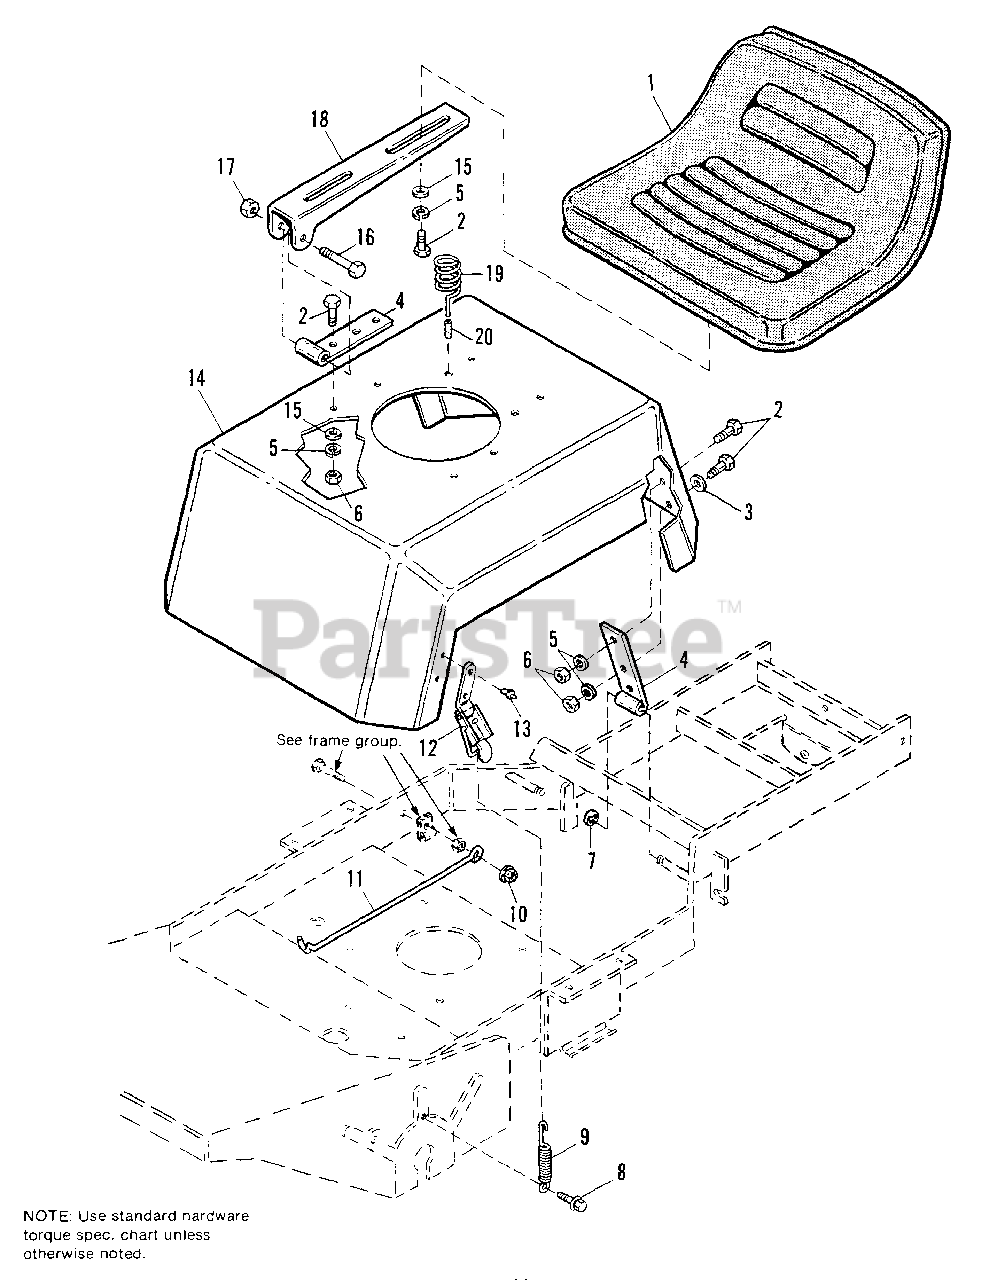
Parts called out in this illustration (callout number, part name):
1	SEAT (Used on 1691330 and on 1691198 after serial no. 1069.)
1	SEAT (Used on 1691198 before serial no. 1070.)
2	CAPSCREW, 5/16-18 x 3/4
3	WASHER
4	HINGE, Seat Deck
5	LOCKWASHER, 5/16
6	NUT, Hex, 5/16-18
7	RING, Retaining
8	SCREW, Taptite, 5/16-18 x 1/2
9	SPRING, Latch
10	NUT, Flange, Lock, 1/4-20
11	ROD, Deck Latch
12	LATCH, Seat, Pull Tight
13	RIVET, Seat Latch
15	WASHER, Flat, 5/16
16	CAPSCREW, 3/8-16 x 2
17	NUT, Hex Lock, 3/8-16
18	HINGE, Upper, Seat
19	SPRING, Seat
20	COVER, Spring
